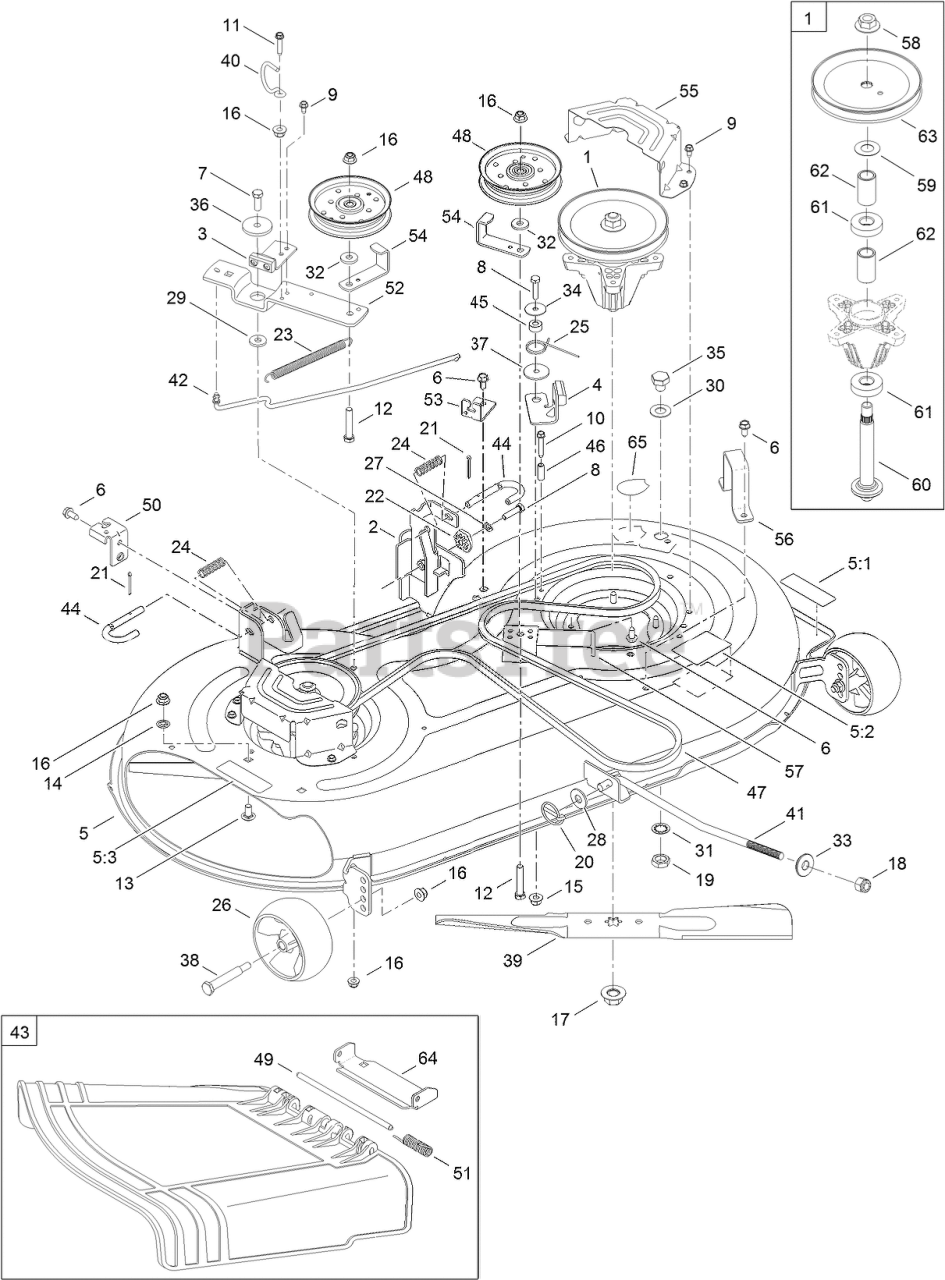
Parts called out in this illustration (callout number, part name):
1	SPINDLE PULLEY ASM
2	LH HANGER BRACKET ASM
3	DECK BRAKE ASM
4	DECK BRAKE ASM
5	DECK ASM
5:1	DECAL-DECK
5:2	DECAL-BELT ROUTING
5:3	DECAL-CHUTE
6	SCREW-TAP
7	SCREW-HH
8	SCREW-HH
9	SCREW-HWHTF
10	SCREW-HWH
11	SCREW-TAP
12	SCREW-HH
13	BOLT-CARR
14	NUT-PUSH
15	NUT-LOCK, FLANGE
16	NUT-LOCK, FLANGE
17	NUT-LOCK, FLANGE
19	NUT-HEX
20	PIN-LYNCH
21	PIN-COTTER
22	GEAR-ADJUSTMENT, DECK
23	SPRING-EXTENSION
24	SPRING-COMPRESSION
25	SPRING-TORSION
26	WHEEL-DECK, FRONT
27	WASHER-LOCK
28	WASHER-FLAT
29	WASHER-FLAT
30	WASHER-FLAT
31	WASHER-LOCK
32	Washer-Flat
33	WASHER-BELLVILLE
34	WASHER-FLAT
36	SPACER-SHOULDER
37	SPACER-SHOULDER
38	BOLT-SHOULDER
39	BLADE-2 IN 1
40	ROD-KEEPER, BELT
41	ROD-LIFT, DECK
42	ROD-BRAKE
43	CHUTE ASM
44	PIN-HANDLE, DECK RELEASE
45	SHOULDER-SPACER
46	SPACER
47	BELT - V
48	PULLEY-IDLER
49	PIN-HINGE
50	BRACKET-CABLE, DECK ENGAGE
51	SPRING-TORSION
52	BRACKET-PIVOT, IDLER
53	BRACKET-CABLE, DECK ENGAGE
54	BRACKET-GUARD, BELT
55	COVER-BELT
56	STOP-LH
57	BRACKET-SUPPORT, IDLER
58	NUT-LOCK, FLANGE
59	WASHER-THRUST
60	SHAFT-SPINDLE
61	BEARING-BALL
62	SPACER
63	PULLEY-DECK
64	BRACKET-PIVOT, CHUTE
65	DECAL-DECK WASH SYSTEM
